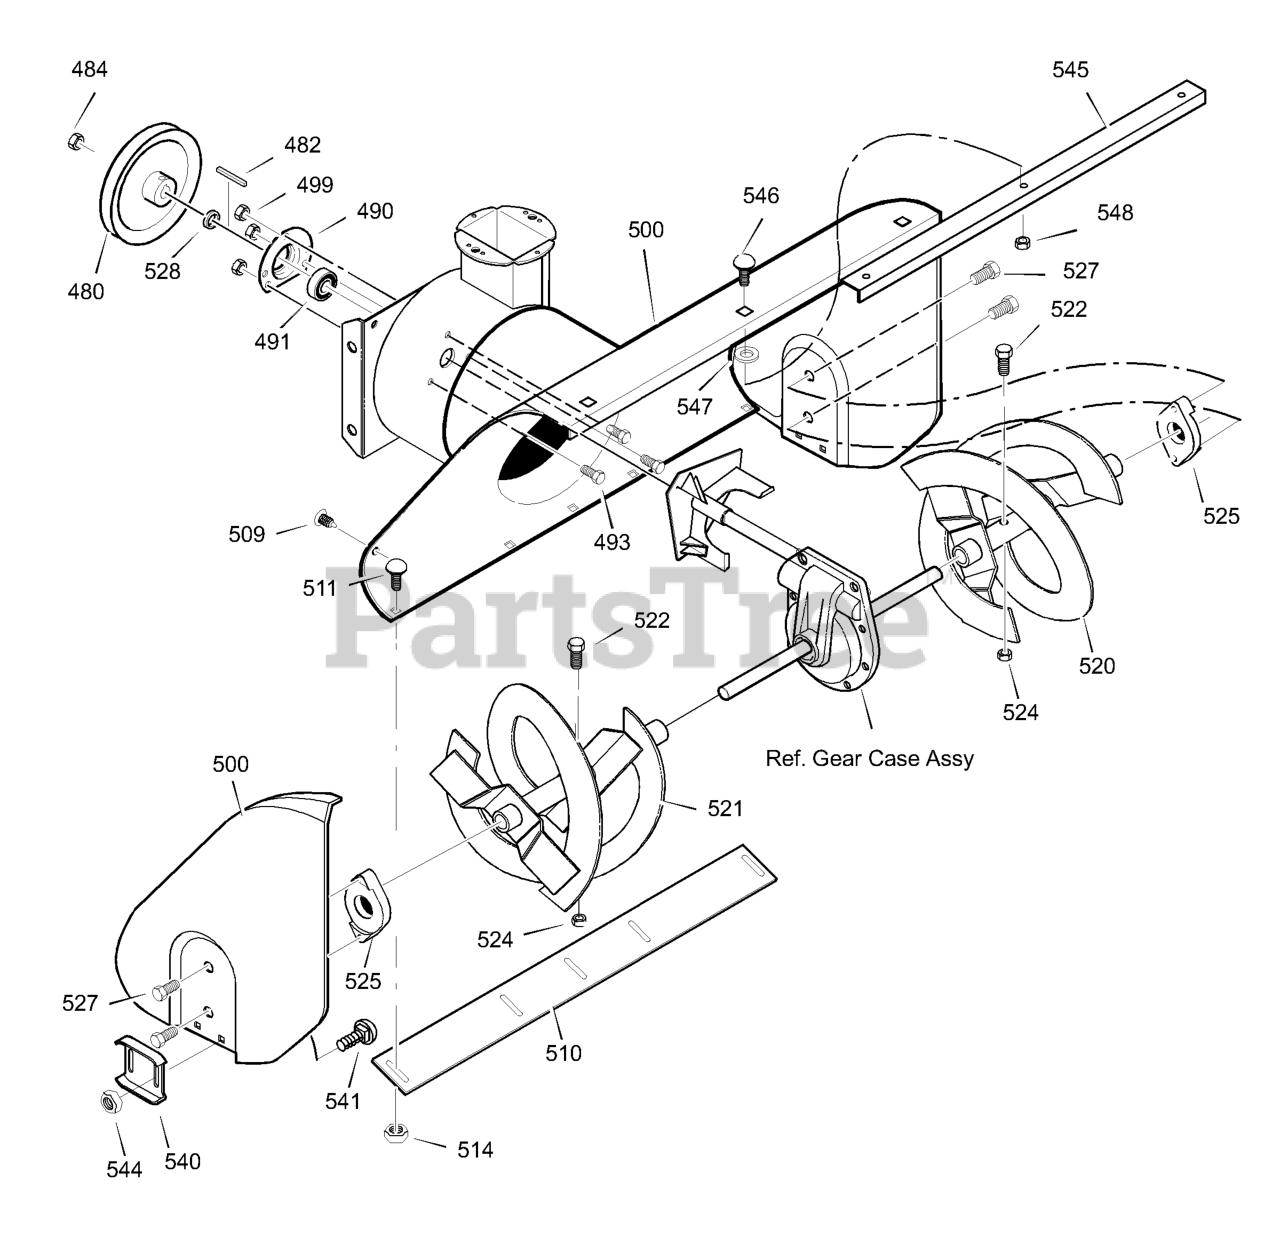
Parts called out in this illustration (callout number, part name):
482	KEY, SQUARE
484	NUT, 1/4-20
485	SPACER, FRICTION PULLEY
490	RETAINER, BALL BRNG
491	BEARING, BALL
493	BOLT, HEX - 0.31-18X0.50
499	NUT, 5/16-18 HEXWDFLLK
500	HOUSING, ASSY
509	PLUG, CHRISTMAS TREE
510	BLADE, SCRAPER
511	BOLT, CARRIAGE
520	AUGER, ASSY, LH
521	AUGER, ASSY, RH
522	BOLT
524	NUT, 5/16-18
525	BEARING,FLANGE
527	SCREW, 5/16-18 x 0.75
536	BOLT
540	SKID, HEIGHT ADJUST
541	BOLT, 5/16-18 X .75
544	NUT, 5/16-18 REGHEX
545	STIFFENER, AUG. ASG.
546	BOLT, CARR.
547	WASHER
